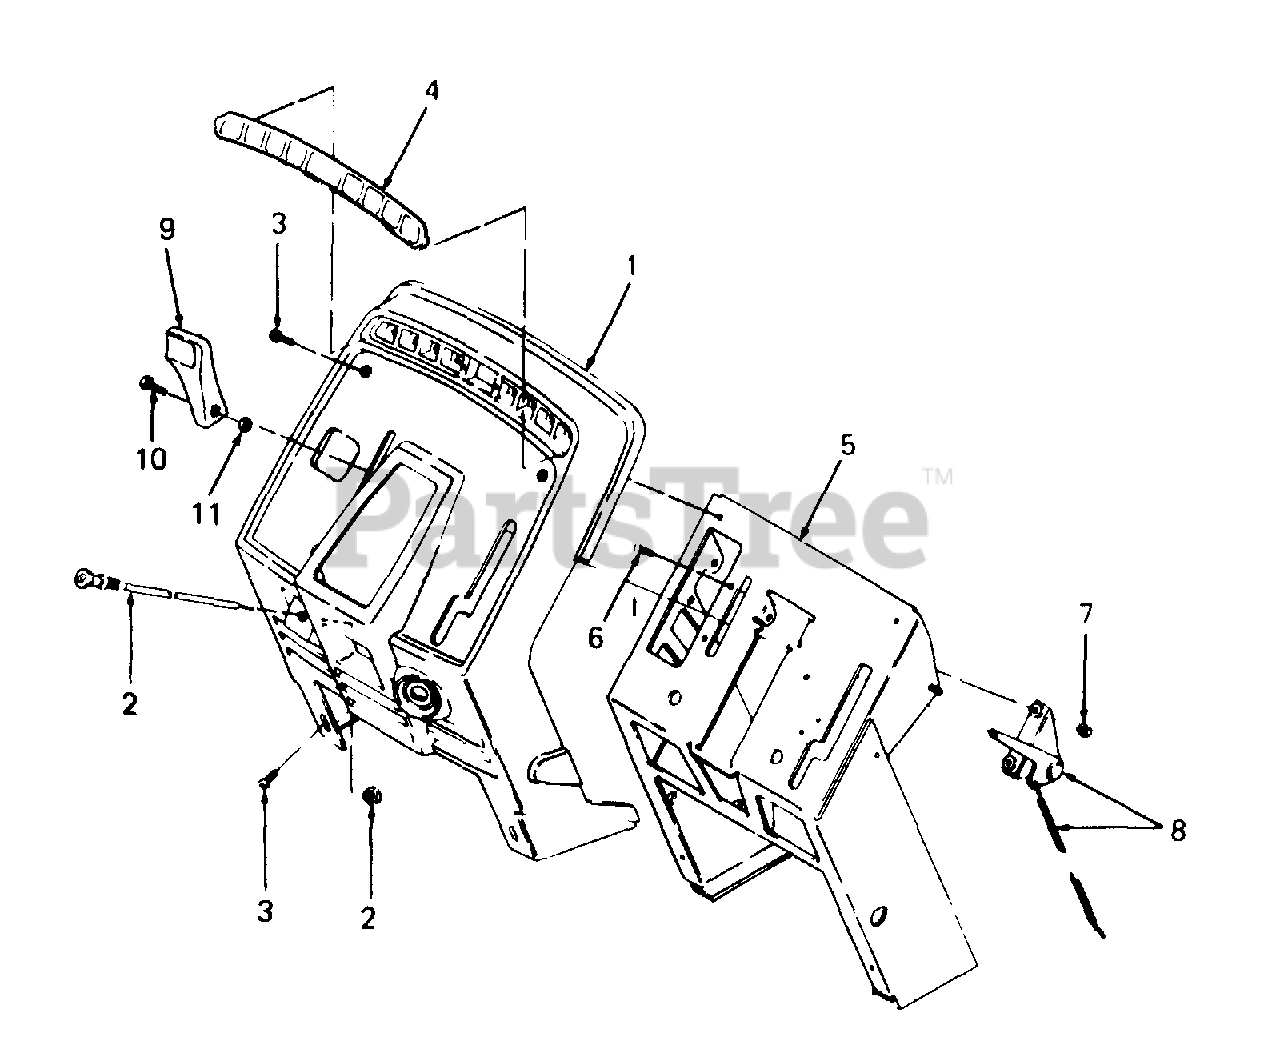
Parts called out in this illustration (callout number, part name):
1	Panel, Instrument
2	Choke Cable w/Nut
3	Screw, Pan Hd Cutting, #10-24 x .75 Lg
4	Label, Dash
7	Nut, Hex Keps, #10-32
8	Control, Throttle
9	Knob, Throttle
10	Screw, Cross Rec Truss Hd, #8-32 x .38 Lg
11	Nut, 8-32
